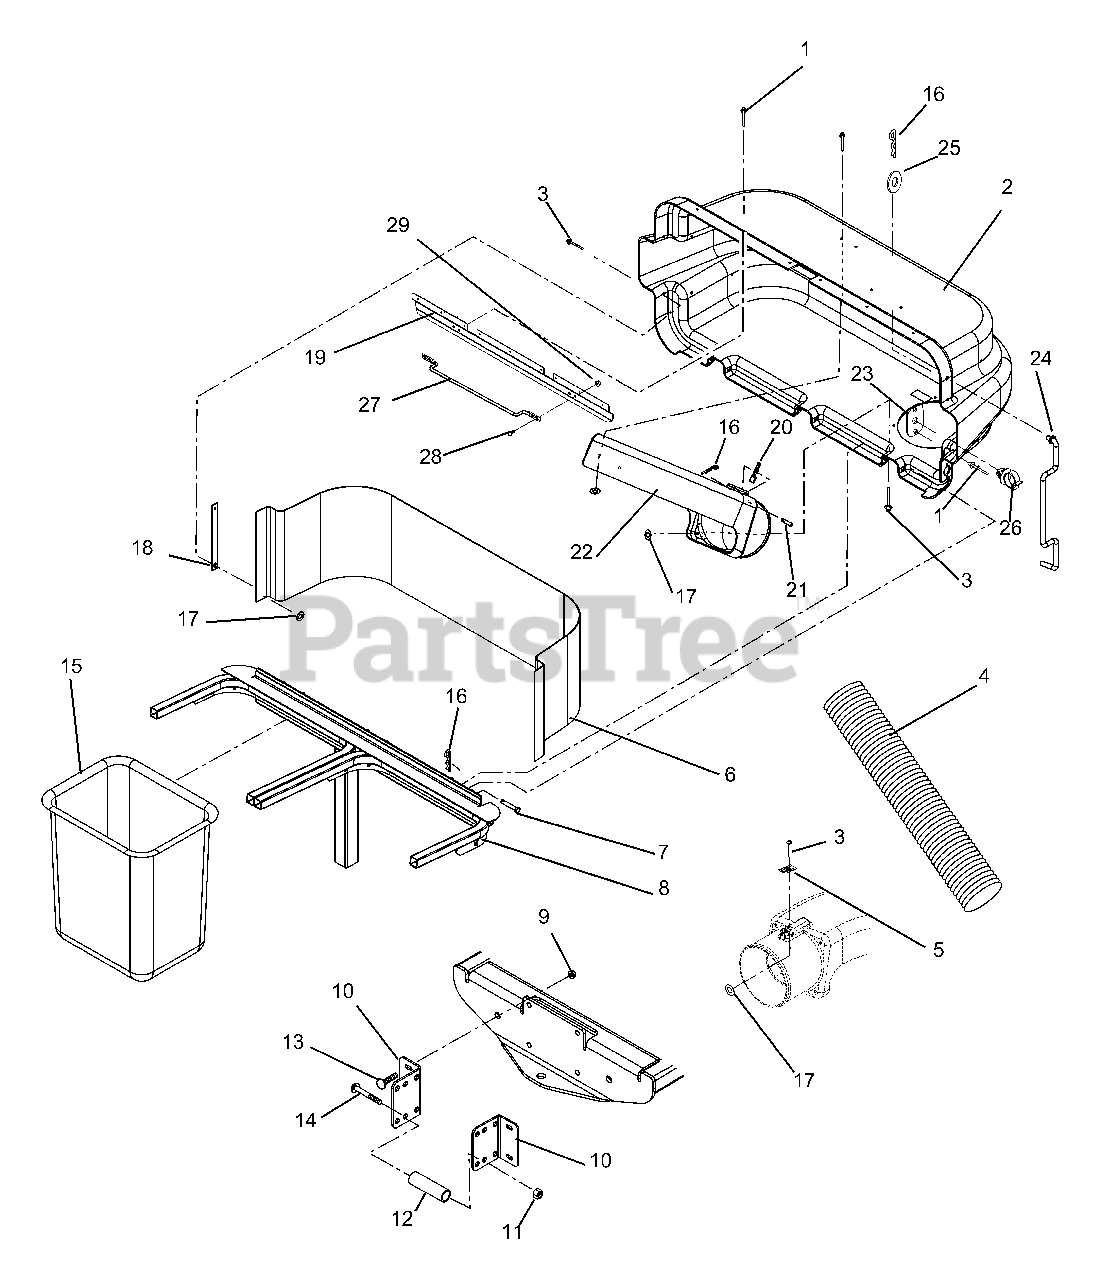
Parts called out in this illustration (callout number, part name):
1	Rivet-Pop .187 x .402
2	Cover, Bagger with Decal
3	Rivet-Pop .187 x .375
4	Hose 7 x 45
5	Thumb Latch
6	Screen, Bagger
7	Pin-Clevis .368/.373 x 3.25
8	Weldment, Bagger Frame
9	Nut-Locking-Top-Flange .38-16
10	Bracket, Bagger Mount
11	Nut-Locking-Top-Flange .50-13
12	Spacer, Pivot
13	Bolt-Round Head Square Neck .38-16 x 1.25 Grade 5
14	Bolt-Hex .50-13 x 3.00 Grade 5
15	Grass Bagger Basket
15	(Gravely Part Number)
16	Pin-Hair
17	Washer-Flat-Steel .219 x .50 x .049
18	Strap, Cover
19	Latch, Cover
20	Indicator, Flow
21	Pin-Clevis .31 x 2.62 Grade 5
22	Boot, Upper
23	Plate, Rod Clip
24	Prop-Rod, Bagger
25	Washer-Flat-Steel .046 x .812 x .065
26	Clip .38
27	Bagger Handle
28	Bolt, Round Head Square Neck .25-20 x .75 Grade 5
29	Nut, Locking Top Flange .25-20
